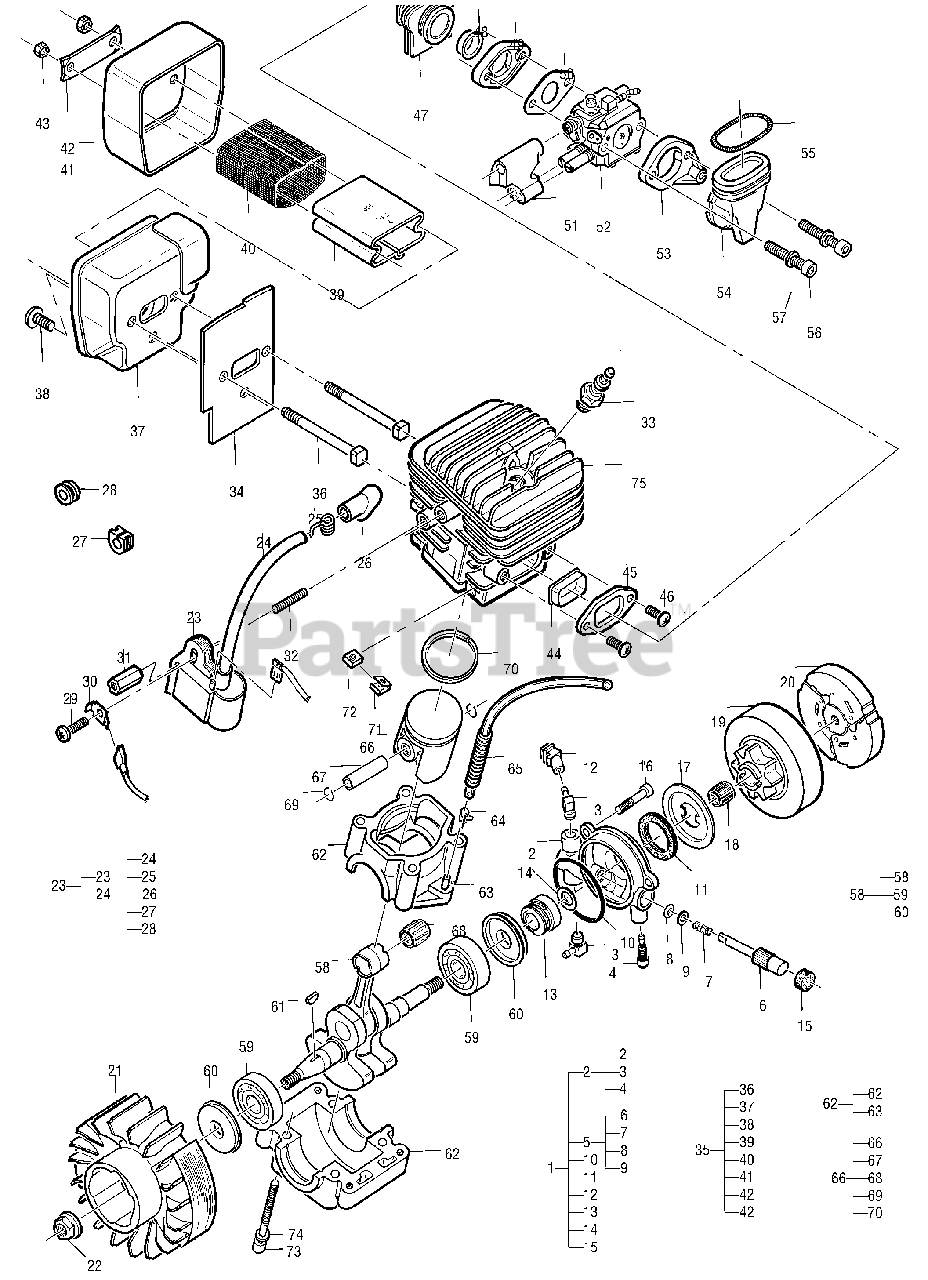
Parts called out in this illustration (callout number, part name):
1	Kit, Oil Pump Asy
2	Pump Asy, Oil
4	Screw, Adj
5	Kit, Gear/Plunger Asy
6	Piston/Gear Asy
7	Spring, Comp
8	O-ring
9	Washer
10	O-Ring, 1.625x.06
11	Washer, Felt
12	Connector, Oil Pump
13	Gear, Worm
15	Seal, Felt
16	Screw, #8 Plast
17	Washer, Clutch Drum
18	Bearing, 10x13x13mm
19	Drum/Sprocket Asy, .325x8T
20	Clutch Asy, Old, Threaded
20	Clutch Asy, New, No Thread
21	Flywheel
22	Nut, Hex 5/16-24
23	Ignition Asy
24	Kit, Spark Plug Wire
25	Connector, Spark
26	Boot, Spark Plug
27	Grommet, H/T Lead
28	Grommet, S/Plug Wire
29	Screw, Tr 10-24x.75 Torx
30	Contact, Ground
31	Spacer, Nut 10-24x.834
32	Stud, 10-24x1.105
33	Spark Plug, RDJ8J
34	Baffle, Muffler Gasket
35	Muffler Asy
36	Screw, Muffler
37	Body Asy, Muffler
38	Screw, 10-24x.5 Tr Torx
39	Baffle, Muffler
40	Screen, Spark Arrester
41	Body, Muffler, Outer
42	Lock Plate
43	Nut, 10-24 Hex Lock
44	Eyelet, Boot
45	Flange, Boot
46	Screw, 10-24x.62 Tr Hd Torx
47	Boot, Carburetor
48	Eyelet, Carburetor
49	Flange, Carburetor
50	Gasket, Carburetor
51	Boot, Carburetor
52	Carburetor Asy
53	Bracket, Carburetor
54	Boot, Intake
55	Spring, Garter
56	Screw, 10-24, Carb Clamp
57	Washer, Special #10
58	C'shaft/Con Rod/Bearing Asy
59	Bearing, Ball
60	Seal, Crankshaft
61	Key, Wdf #206
62	Crankcase/Fitting Asy
63	Fitting, Pulse Line
64	Clamp, Wire, Hose 1/4"
65	Conduit, Flex
67	Pin, Piston
68	Bearing, Piston Pin
69	Ring, Retaining
71	Retainer, Nut
72	Nut, 10-24 Sq
73	Screw, 10-24x2.75 Torx
74	Washer, #10 Special
75	Short Block Asy
